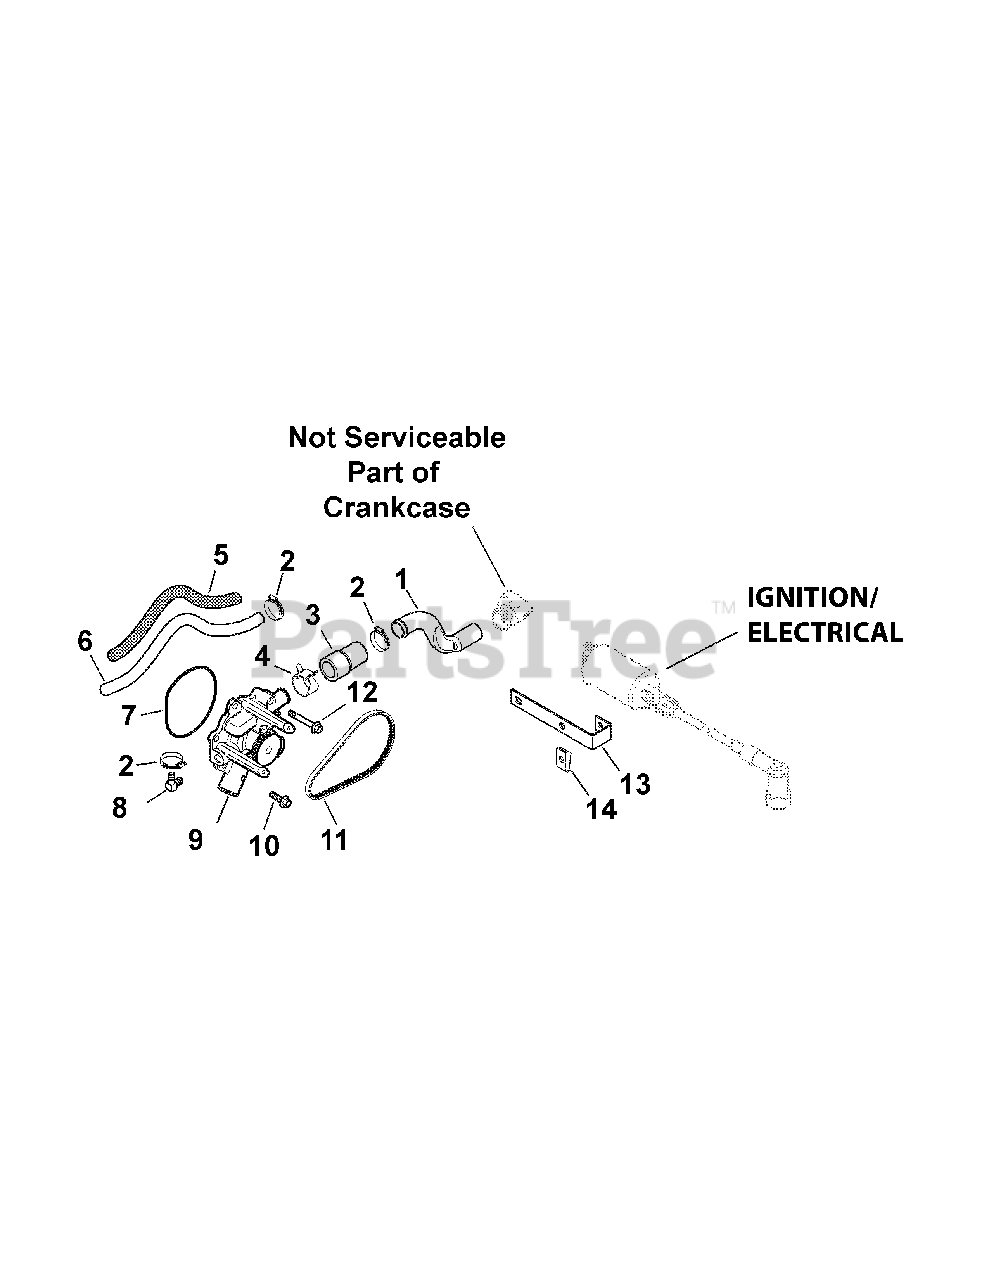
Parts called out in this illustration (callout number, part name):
1	Tube, Crossover
2	Clamp, Hose
3	Tube, Crossover
5	Sleeve, Insulating 14"
6	Hose, By-pass
9	Pump, Water
10	Screw, Flg, M6 x 1.0 x 20
11	Belt, Water Pump
12	Screw, Flg, M6 x 1.0 x 40
13	Bracket, Ignition Coil (EFI)
